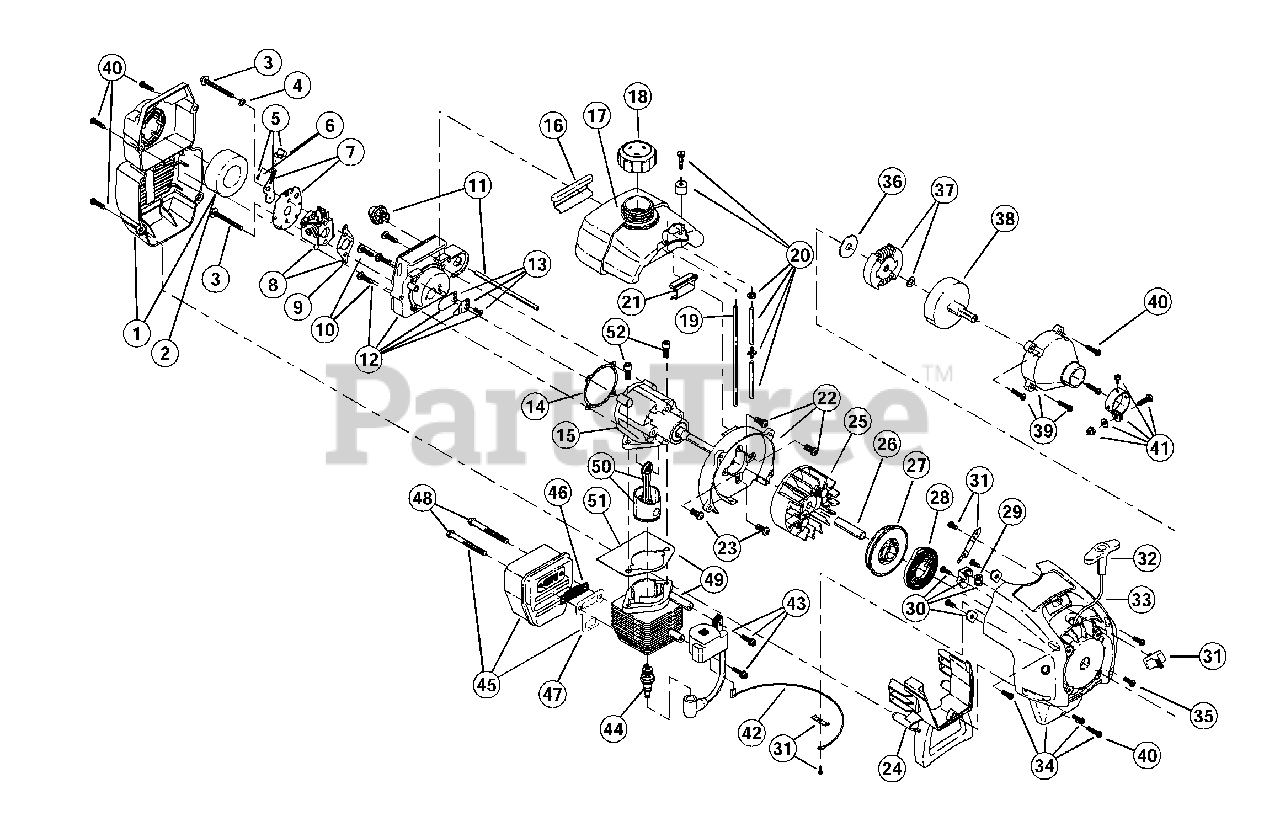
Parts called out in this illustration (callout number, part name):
1	Air Cleaner/Muffler Cover Assembly
2	Air Cleaner Filter
3	Carburetor Mounting Screw Assembly
4	Wavey Washer
5	Choke Lever Assembly
6	Choke Knob and Screw
7	Choke Lever and Plate
8	Carburetor Assembly
9	Carburetor Gasket
10	Carb Mount Screw
11	Primer and Hose Assembly
12	Carb Mount Assembly
13	Reed Assembly
14	Carburetor Mount Gasket
15	Crank Case Service Assembly
16	Rear Mounting Pad
17	Fuel Tank Assembly
18	Fuel Cap Assembly
19	Fuel Return Line
20	Fuel Line Assembly
21	Front Mounting Pad
22	Shroud Assembly
23	Shroud Screw
24	Shroud Extension & Stand
25	Flywheel Assembly
27	Recoil Pulley Assembly
28	Recoil Spring
29	Rope Guide
30	Pulley Retainer Assembly
31	Switch Assembly
32	Pull Handle
34	Starter Housing Assembly
35	Housing Screw
36	Clutch Washer
37	Clutch Rotor Assembly
38	Clutch Drum Assembly
39	Clutch Cover Assembly
40	Cover Screw
41	Upper Clamp Assembly
42	Wire Lead
43	Module Assembly
44	Spark Plug
45	Muffler Assembly
46	Spark Arrestor
47	Exhaust Gasket
48	Muffler Mounting Bolt Assembly
49	Cylinder Assembly
50	Piston and Rod Assembly
51	Cylinder Gasket
52	Cylinder Bolt
